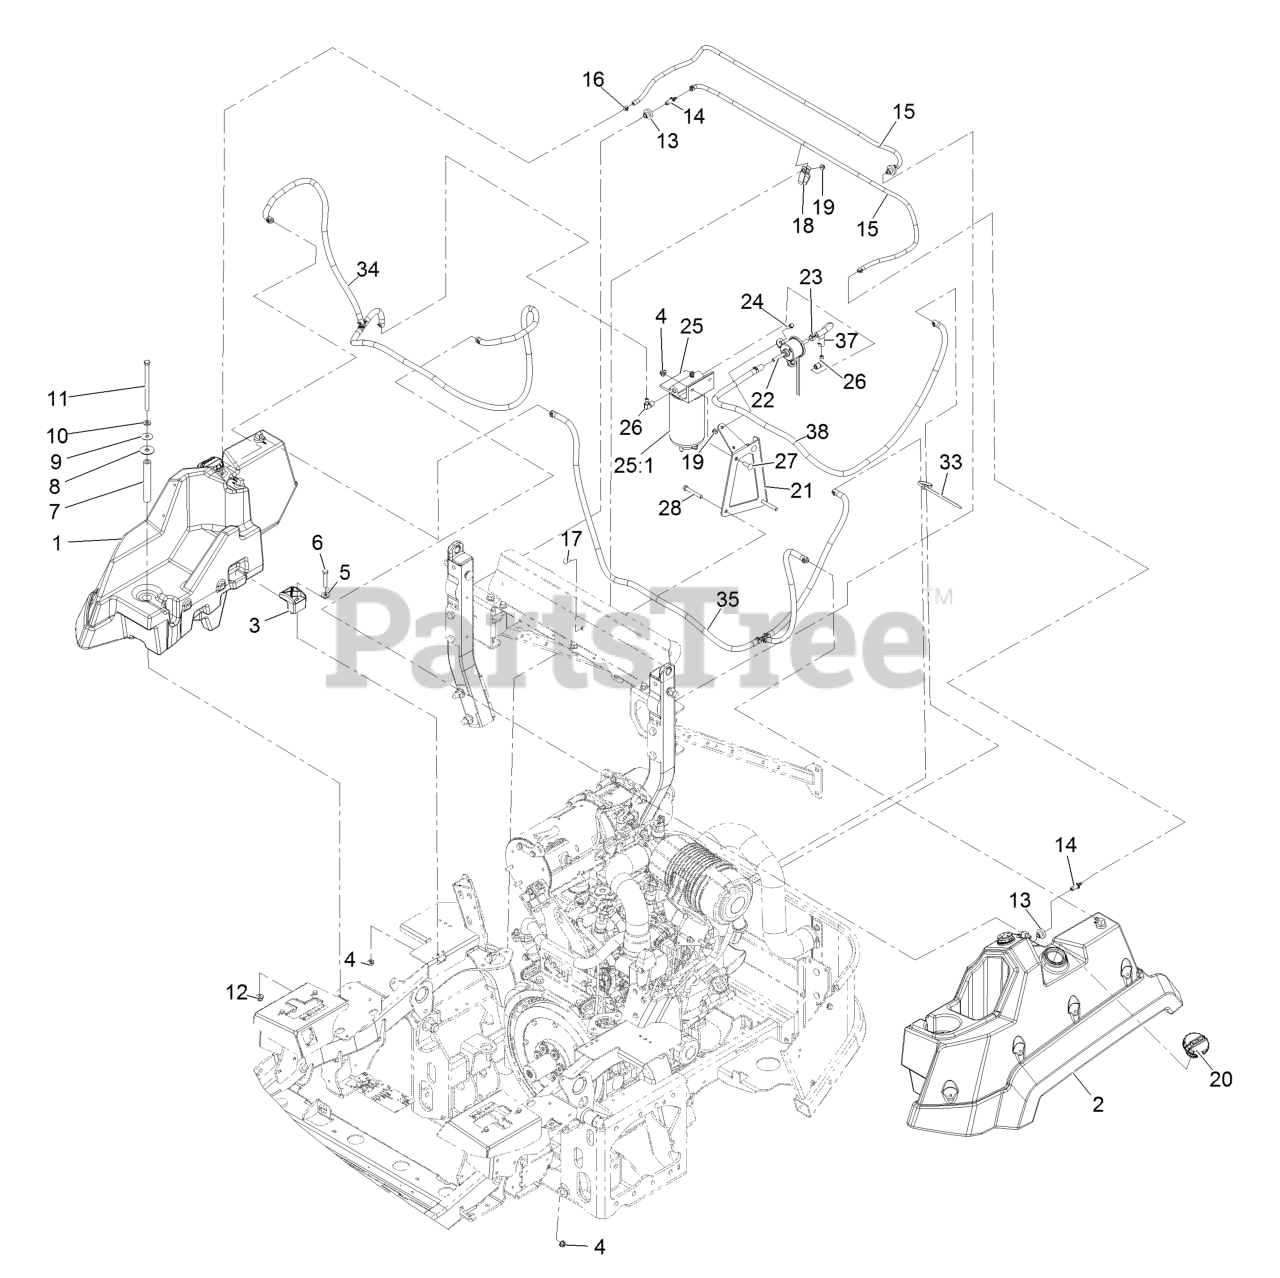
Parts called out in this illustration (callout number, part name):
1	RH Fuel Tank ASM
2	LH Fuel Tank ASM
4	Nut-Nyloc 5/16-18 Flg
5	Washer-5/16 Std
6	Screw-HH
7	Tube-Spacer
8	Washer-Rubber
9	Washer-Plain
10	Washer-3/8 SAE
11	Screw-HH
12	Nut-Nyloc 3/8-16 Flg
13	Bushing
14	Fitting-Orifice, Straight
15	Hose-Vent, Tank
16	Clamp-Hose
17	Bolt-Carriage 1/4-20 X 5/8
18	Clamp-Hose
19	Nut-Nyloc 1/4-20 Flg
20	Cap-Fuel, Diesel
21	Bracket-Filter, Fuel
22	Pump-Fuel, Electric
23	Clamp-Hose
24	Screw-Machine 1/4-20 X 3/4
25	Separator Filter ASM
25	Filter-Water/Fuel Seperator
25:1	Filter-Fuel/Water Separator
26	Fitting-Elb, 90
27	Bolt-Carriage 5/16-18 X 1 Sp
28	Screw-HH 5/16-18 X 2 1/4
33	Tie-Cable 7 15/16 (Large)
34	Fuel Suction Line ASM
35	Fuel Return Line ASM
37	Hose-Fuel
38	Hose-Fuel
